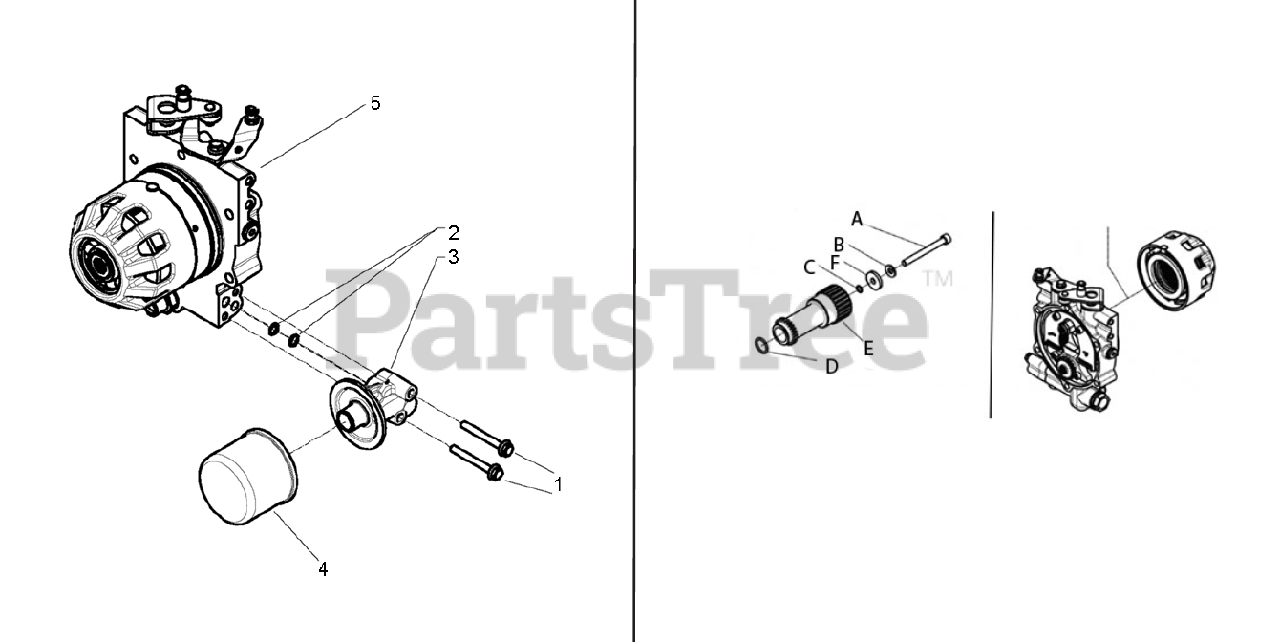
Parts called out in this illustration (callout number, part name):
2	O-RING 108 (8,73X1,78)
3	CONNECTION
4	FILTER
5	HYDRAULIC BLOCK KD440
A	BOLT M8X80
B	WASHER
C	O-RING
D	O-RING 3075
F	WASHER
